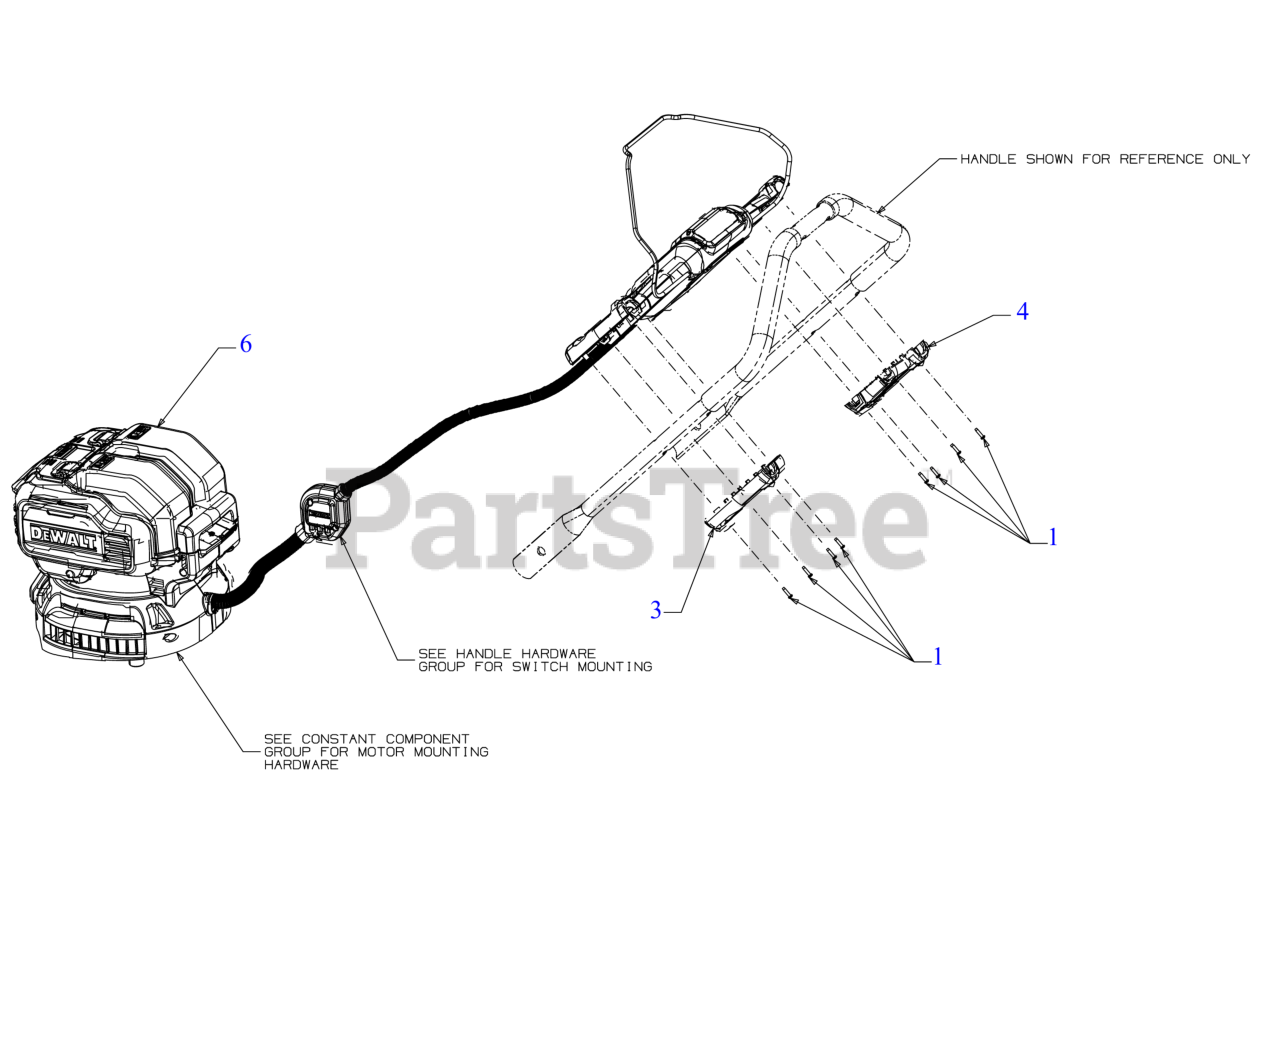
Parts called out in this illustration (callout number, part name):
1	SCREW-TAP PLASTIC #6-19 X 0.62
3	HANDLE PANEL COVER (REAR) (LH) (YELLOW)
4	HANDLE PANEL COVER (REAR) (RH) (YELLOW)
6	MOTOR/PANEL ASSEMBLY
